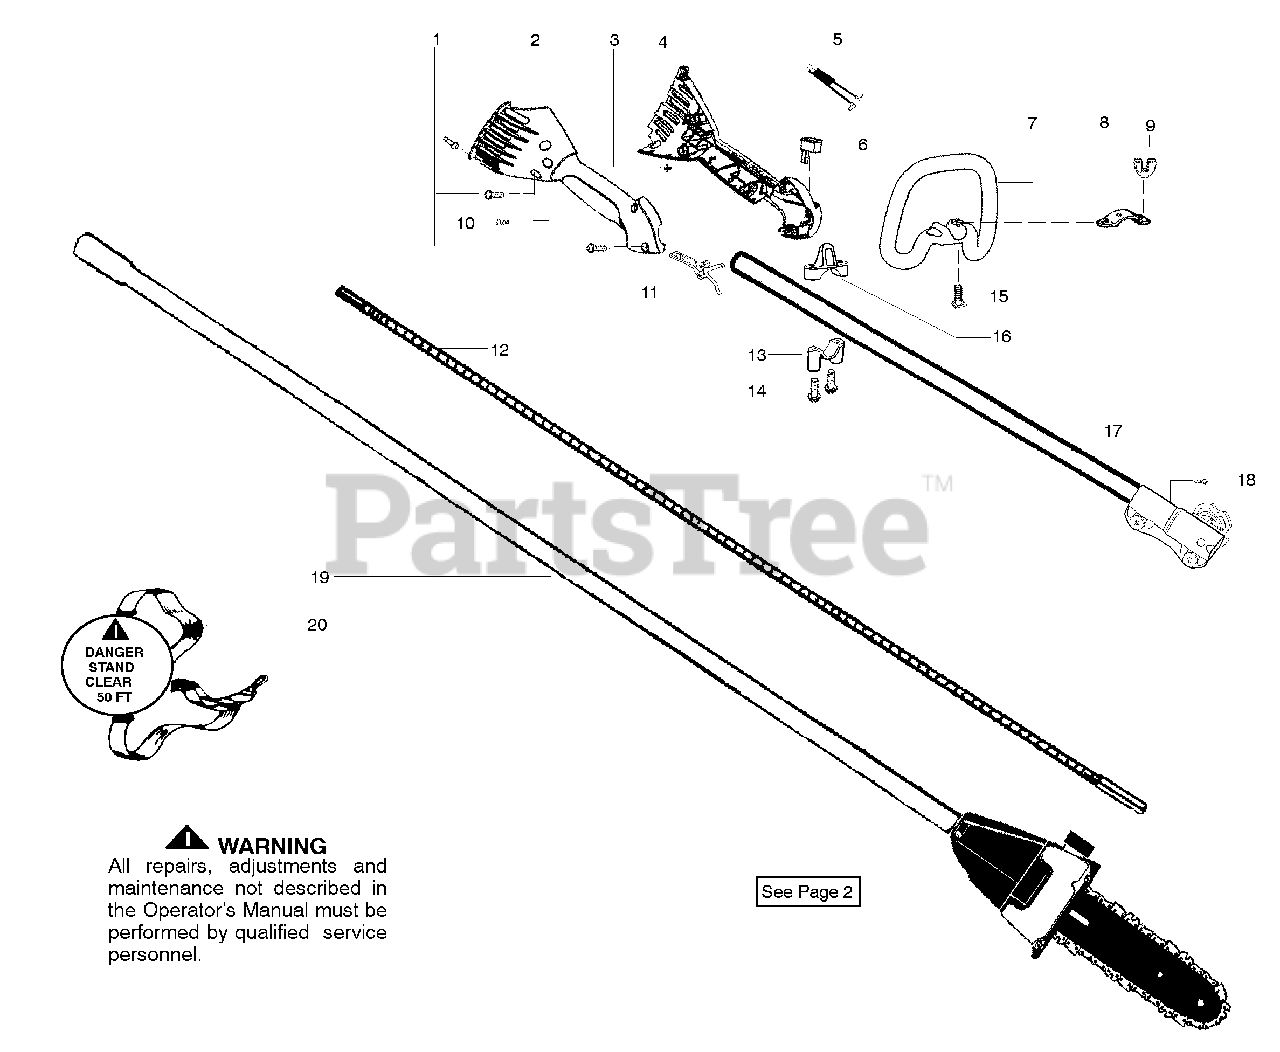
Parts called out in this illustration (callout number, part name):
2	Hsg.-Throttle right
3	Screw-Cable Ret.
4	Hsg.-Throttle left
7	Handle
9	Wingnut
10	Screw-Align
11	Trigger-Throttle
17	Kit-Upper Shaft
19	Assy-Driveshaft
20	Assy-Shoulder Strap
